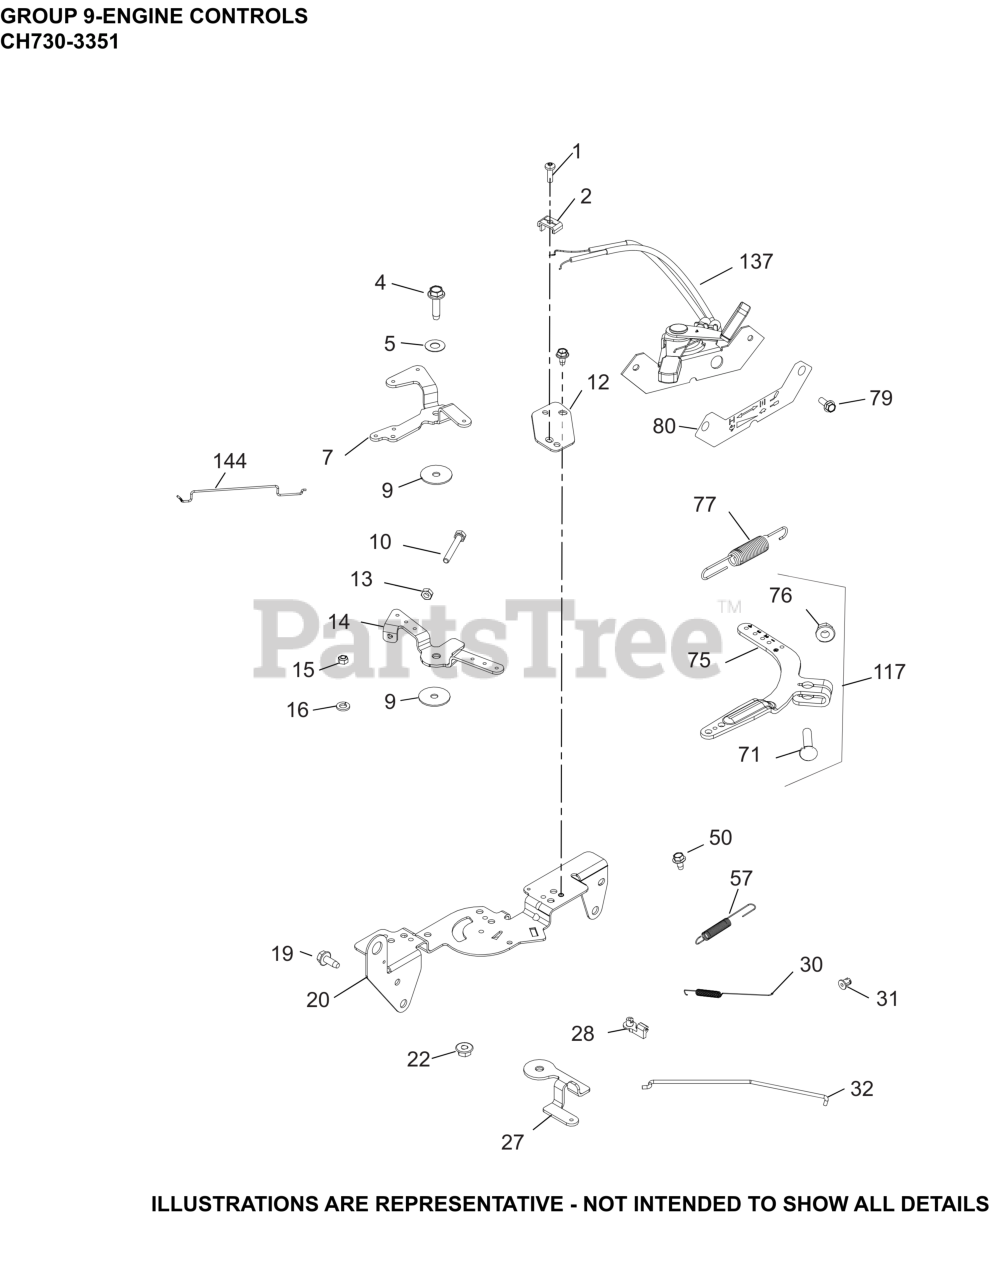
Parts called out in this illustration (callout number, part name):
1	SCREW, THREAD FORMING
2	CLAMP, CABLE CABLE
4	SCREW, THD FRM-USE 25 086 473-S
5	WASHER, SPRING 1/4"
7	LEVER, CHOKE
9	WASHER, FLAT 5.5 MM
10	SCREW, CAP M4X.7X30
12	BRACKET, CABLE SUPPORT
13	NUT, M4X0.7
14	LEVER, THROTTLE CONTROL
15	NUT, FLG M5X.8
16	WASHER, SPRING LOCK 1/4"
19	SCREW, THREAD FORMING
20	BRACKET, CONTROL
22	NUT, LOCK M5X.8
27	LEVER, THROTTLE ACTUATOR
28	BUSHING, THROTTLE LINKAGE
30	SPRING, LINKAGE
31	BUSHING, LINKAGE RETAINING
32	LINKAGE, THROTTLE
50	SCREW, THREAD FORMING
57	SPRING, THROTTLE LIMITER
71	BOLT, RD HD SQ NECK M6X1.0X25
75	LEVER, GOVERNOR - (#2409069S)
76	NUT, FLG M6X1.0
77	SPRING, GOVERNOR (BLACK)
79	SCREW, HI-LOW
80	DECAL, CONTROL PANEL
117	LEVER, GOVERNOR ASSEMBLY
137	CABLE ASSEMBLY, DUAL CONTROL
144	LINKAGE, CHOKE
